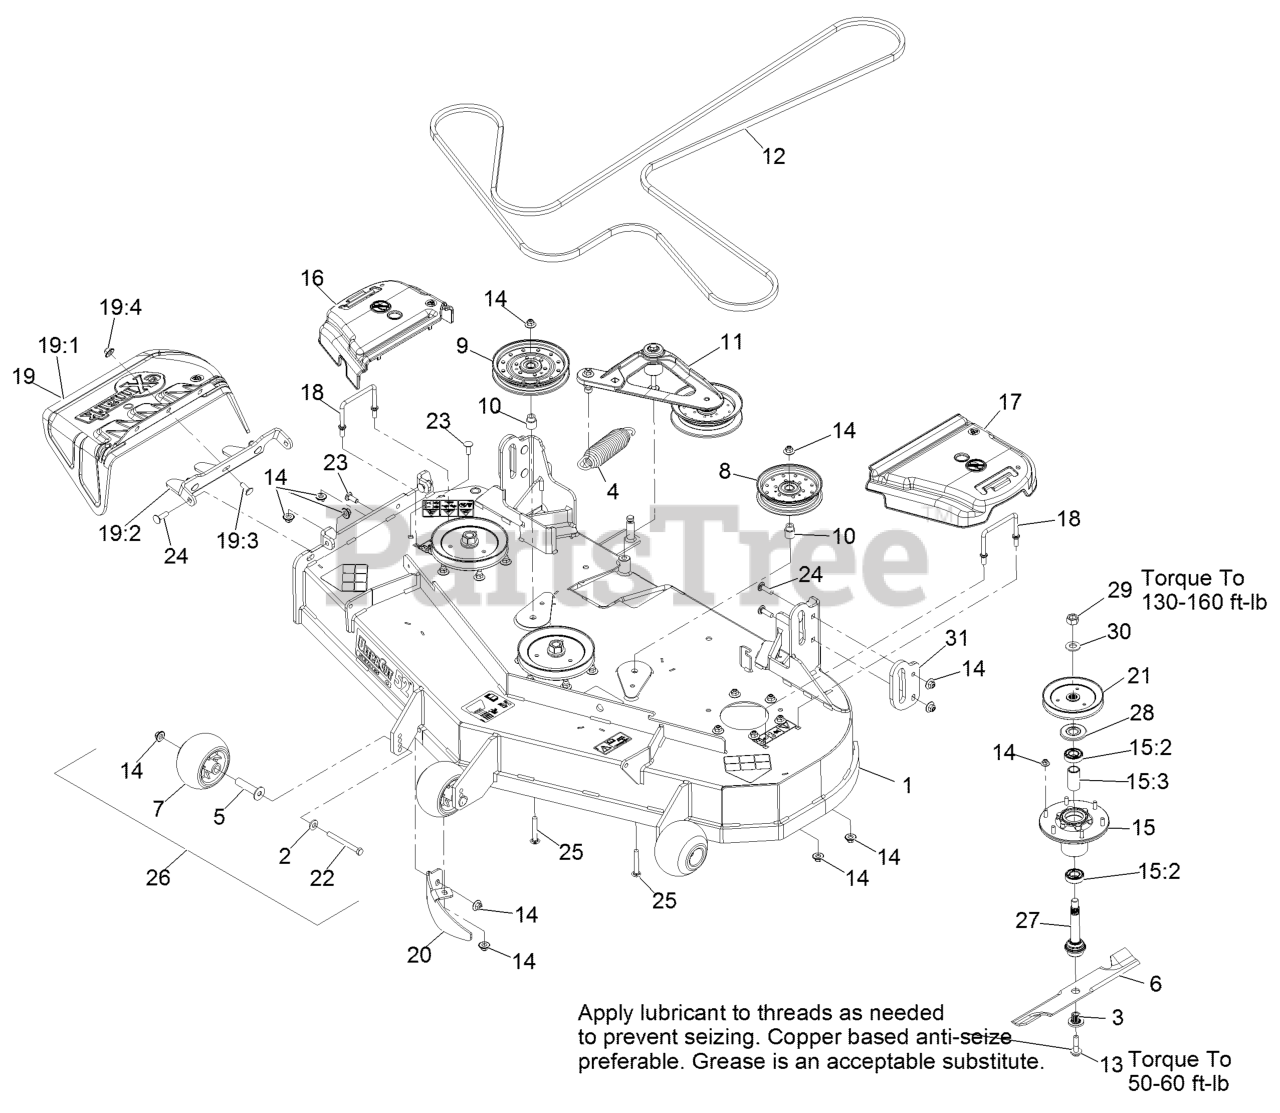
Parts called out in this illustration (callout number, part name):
1	ASM, DECK W/DECALS 524
2	WASHER-BELLEVILLE
3	BUSHING,SPLINED
4	SPRING-EXTENSION
5	AXLE, ROLLER
7	ROLLER-SCALP, ANTI
10	BUSHING-IDLER
11	DECK IDLER ASM
12	BELT,V-B X 186.00"
13	SCREW,SEMS 1/2-20 X 2.19
14	Nut-Nyloc 3/8-16 Flg
15	ASM-CUTTER HSG WITH BEARINGS
15:2	BEARING-BALL
15:3	SPACER-BEARING
16	COVER-BELT, RH
17	COVER-BELT, LH
18	WIREFORM-COVER
19	ASM,DISCHARGE CHUTE
19:1	CHUTE,DISCHARGE
19:2	BRACKET,DISCHARGE CHUTE
19:3	SCREW-CARR
19:4	Nut-Nyloc 3/8-16 Flg
20	BAFFLE-DOGLEG, LZE-PNS-52
21	SHEAVE,BLADE DRIVE 6.50
22	SCREW-HH 3/8-16 X 3 3/4 GR 8
23	SCREW-CARR
24	Bolt-Carriage 3/8-16 X 1 1/4
25	SCREW-CARR
26	KIT, ANTI-SCALP ROLLER
27	ASM-SPINDLE AND SEAL
28	GUARD,BEARING TOP .989
29	NUT-HEX
31	PLATE-REINF, PUSH TOWER
